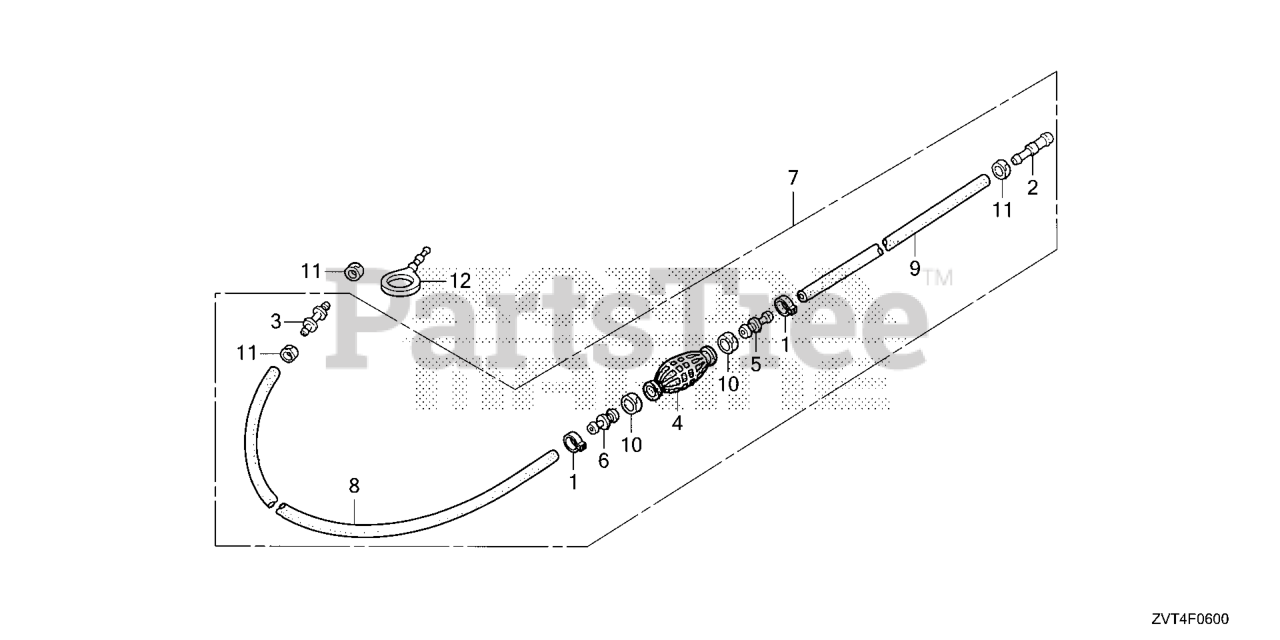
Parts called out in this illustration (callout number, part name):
1	CLAMP, FUEL TUBE (14.0) (CONNECTOR TYPE)
2	JOINT, FUEL TUBE (JOINT TYPE)
3	JOINT, FUEL TUBE
4	BULB, PRIMER
5	VALVE, IN.
6	VALVE, OUTLET
7	TUBE, FUEL TANK
8	TUBE, FUEL LONG (75)
10	BAND, TUBE CLIP (20MM)
11	BAND, TUBE CLIP (12.5MM)
12	PLUG, FUEL TUBE
